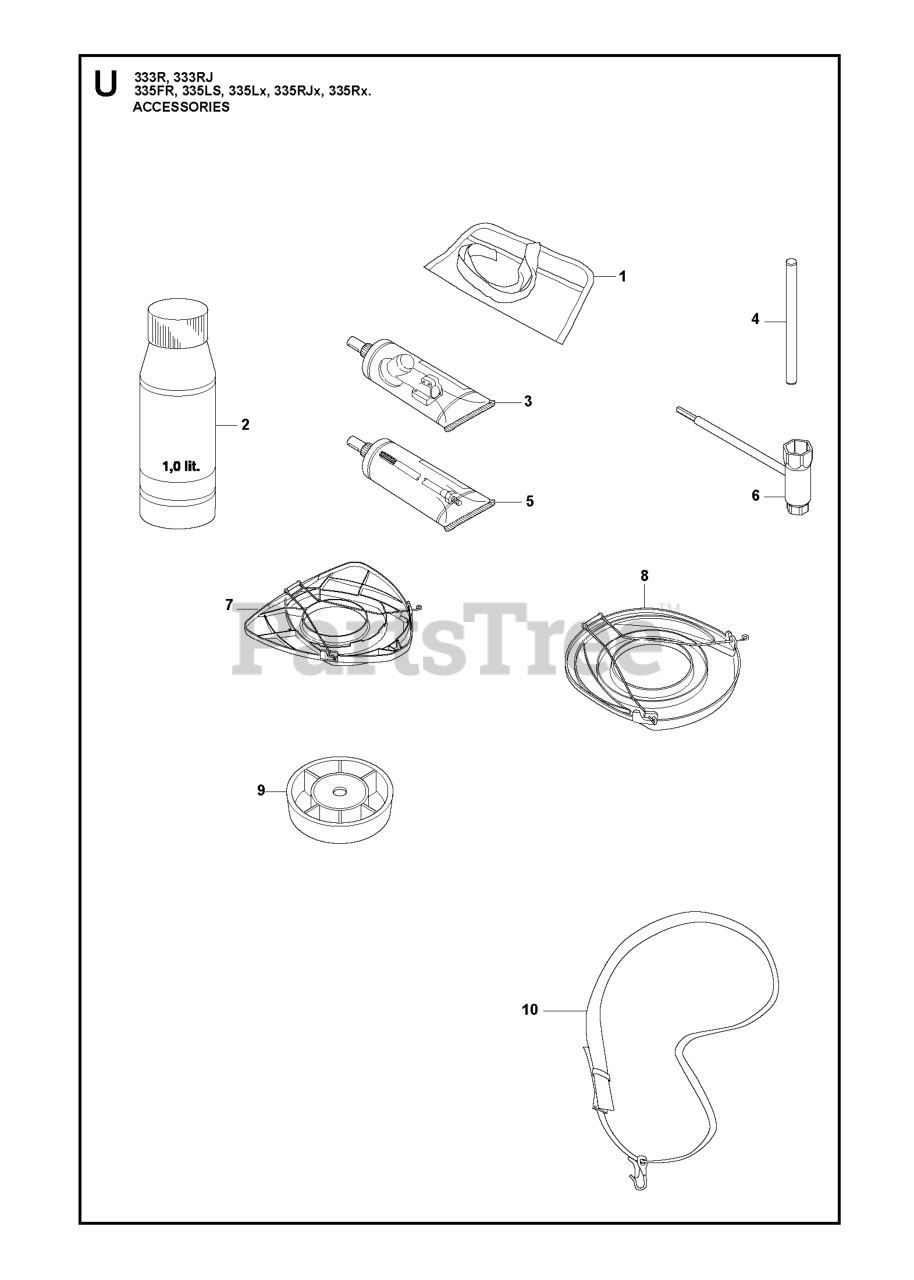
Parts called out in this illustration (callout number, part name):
2	Air Filter Oil 1l.
3	BEVEL GEAR GREASE
4	LOCKING PIN
5	DRIVE SHAFT GREASE (200 G)
6	RP COMBI TOOL
7	TRANSPORT GUARD
8	BLADE GUARD TRANSPORT
9	SUPPORT CUP
10	Harness - Diagonal with sign
10	Harness-w/o warning
